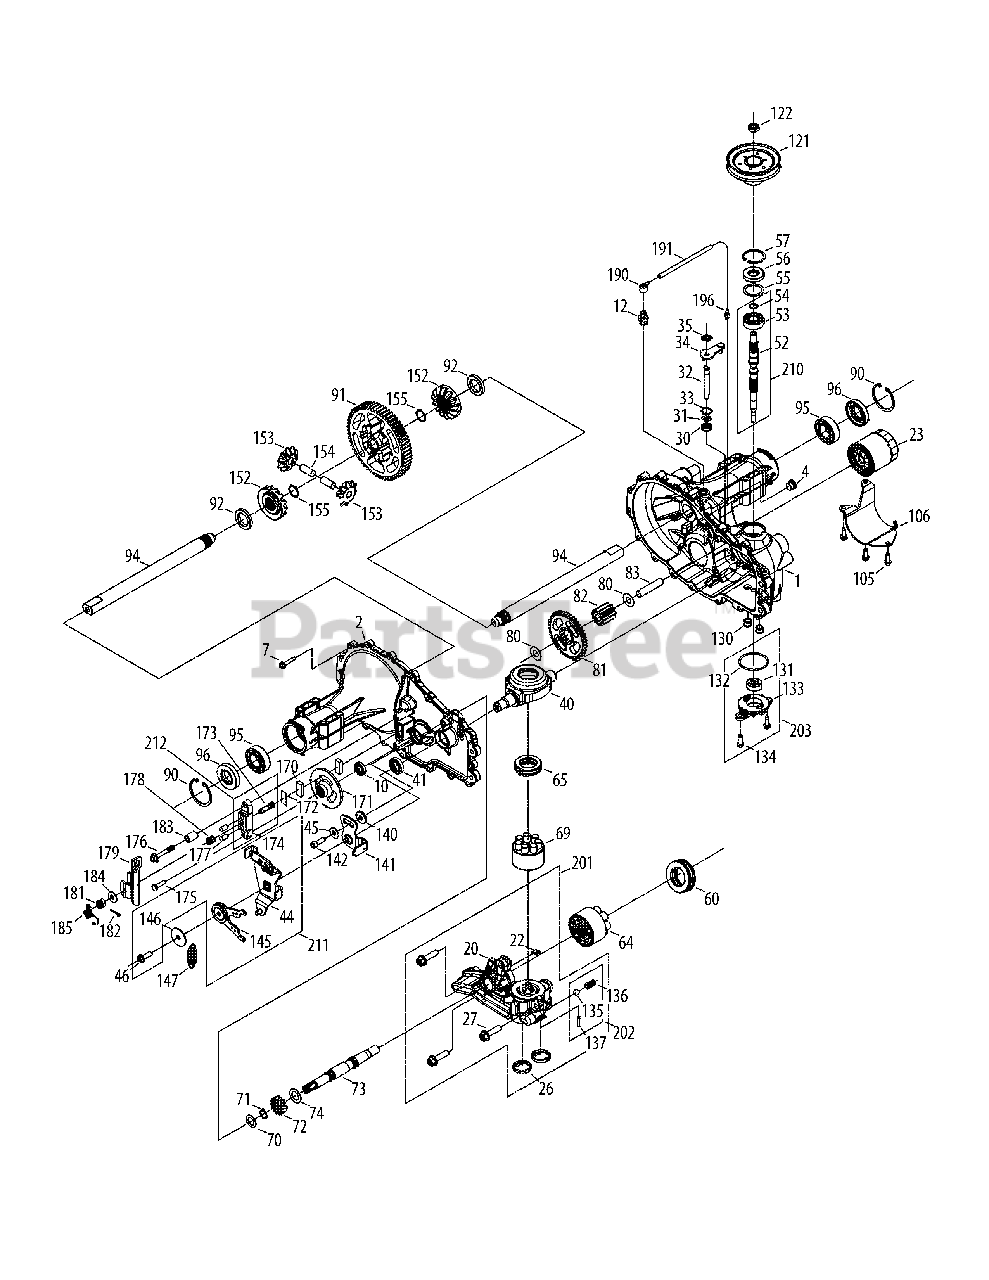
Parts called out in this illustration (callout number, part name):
1	Kit, Housing, Main
1	Housing, Main
1	Pin, Standard Headless
1	Bushing, .624 x .719 x .562
1	Bushing, .865 x .985 x .790
1	Bearing, Flange 1.0 x 1.376 x .99
2	Kit, Housing, Side
2	Housing, Side
2	Bushing, .624 x .729 x .562
2	Bushing, .865 x .985 x .790
2	Bearing, Flange 1.0 x 1.376 x .99
4	Plug, 9/16-18 (Metal)
006	Pin, Standard Headless
7	HFHCS 1/4-20 x 1.25
10	Seal, Lip .625 x 1.0
010	Seal, Lip .625 x 1.0
12	Assembly, Fitting, Metal
020	Center Section, LH, CHRG
22	Plate, Bypass
022	Plate, Bypass
23	Filter, Oil
024	Check Plug
025	Check Plug
26	Seal, Plug 1.250 x .250
026	Seal, Plug 1.250 x .250
27	HFHCS 3/8-16 x 1.5 (Patch)
027	HFHCS 3/8-16 x 1.5 (Patch)
30	Seal, Lip .375 x .75 x .25
030	Seal, Lip .375 x .75 x .25
31	Ring, Retaining .375 External
031	Ring, Ret .375 External
32	Rod, Bypass
33	Ring, Retaining .750 Internal
033	Ring, Ret .750 Internal
34	Arm, Bypass
35	Ring, Retaining .375 Internal
035	Ring, Ret .375 External
40	Trunnion, Swashplate
41	Seal, Lip 18 x 32 x 7
041	Seal, Lip 18 x 32 x 7
044	Arm, Control
45	Washer, .24 x .88 x .05
46	TWHCS 5.16-24 x 1.00 (Patch)
046	TWHCS 5.16-24 x 1.00 (Patch)
046	Screw 5/16-24 x 1.00 (Patch)
052	Shaft, Input
053	Brg, Ball 17 x 40 x 12 Open 6203
054	Ring, Ret Wire .561 ID
55	Washer, 1.23 x 1.56 x .04
56	Seal, Lip 17 x 40 x 17
056	Seal, Lip 17 x 40 x 7
57	Ring, Retaining 1.575 Internal
057	Ring, Ret 1.575 Internal
60	Bearing, Thrust
64	Assembly, Cylinder Block, 16cc
65	Bearing, Thrust Ball 30 x 52 x 13
69	Assembly, Block 7 Piston
70	Washer, .63 x 1.0 x .05
71	Ring, Retaining .625 External
071	Ring, Ret .625 x External
72	Gear, 14T
73	Shaft, Motor
74	Washer, .72 x 1.16 x .04
80	Washer, .5 x 1.0 x .03
81	Gear, 45T
82	Gear, 11T
83	Pin, Jackshaft
90	Ring, Retaining 2.06 Internal
090	Ring, Ret .206 Internal
91	Gear, 60T
92	Spacer, 1.04 x 1.65 x .22
94	Shaft, Axle 1.00 x 13.37, DD
95	Bearing, Ball 1.0 x 52 x 15
96	Seal, Lip 25 x 52 x 10 TC (Gray)
096	Seal, Lip 25 x 52 x 10 TC (Gray)
105	HFHCS 1/4-20 x .75
106	Guard, Filter, LH
121	Pulley, 4.0"
122	Hex Lock Nut 1/2-20 (Nylon Insert)
123	Screw Hex 1/4-20 x .875
130	Tube, Connecting
131	Gerorter Assembly (1.9cc/REV)
132	O-Ring - 137, .103 x 2.050
133	Cover, Charge Pump
134	Screw, Pan Head 1/4-20 x .75
135	Ball, Steel 7/16"
136	Spring, Relief .42 x .75
137	Pin, Spring .125 x .875
140	Spacer, .320 x 1.005 x .179
141	Assembly, RTN, Neutral Arm
142	SHCS 5/16-24 x 1 Patch
145	Assembly, RTN Bidirectional
146	Washer, .343 x 1.500 x .062
147	Spring, Extension RTN - 44 LBS
152	Gear, Bevel 14T Spline ID
153	Gear, Bevel 10T
154	Pin, .499 x 1.20
155	Ring, Spiral Retaining - 87
155	Ring, Sprial Ret .875
170	Puck, Brake
171	Rotor, Brake
172	Plate, Puck
173	Bolt, Square Head
174	Brake Yoke
175	Bolt, Hex Head 1/4-20 x 1 w/ Patch
176	Bolt, Hex Head 1/4-20 x 2 w/ Patch
177	Pin, Brk .31 x .73 Plated
178	Spring, Comp Brake Anti-Drag
179	Arm, Brake
181	Nut, Castle 5/16-24 PL
182	Pin, Cotter 3/32 x 3/4
183	Spacer, .26 x .57 x .87
184	Washer, .27 x .88 x .12
185	Spring, Brake Arm Bias
190	Cap, Barbed
191	Hose, .28 x .15 x 10.00
196	Fitting, Barbed
201	Kit, Center Section, LH, CHRG
202	Kit, Charge Relief
203	Kit, Charge
210	Kit, Input Shaft
211	Kit, RTN Bidirectional
212	Kit, Brake-Yoke
